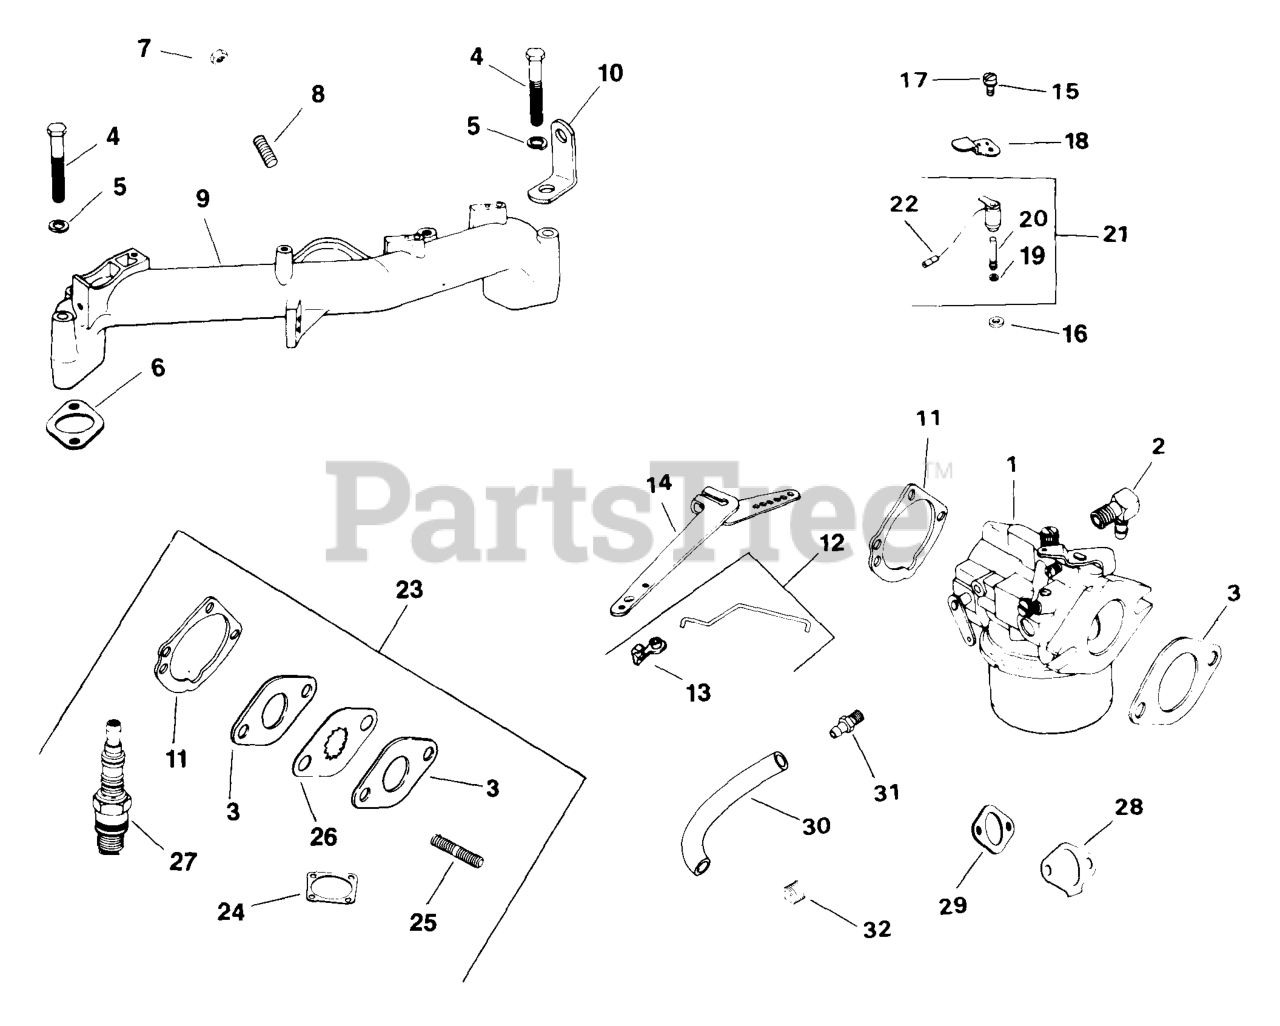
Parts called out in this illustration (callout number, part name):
1	Kit, Adjustable Jet Carburetor
2	Connector, 90ø Hose
3	Gasket, Carburetor
4	Screw, H.C. 5/16-18x2-3/4"
5	Washer, Lock 5/16"
6	Gasket, Intake Manifold
7	Nut, Hex. Jam 5/16-18
8	Stud 5/16-18x1"
9	Manifold, Intake
10	Strap, Lifting
11	Gasket, Air Cleaner
12	Kit, Governor Linkage
13	Bushing
14	Arm, Governor
